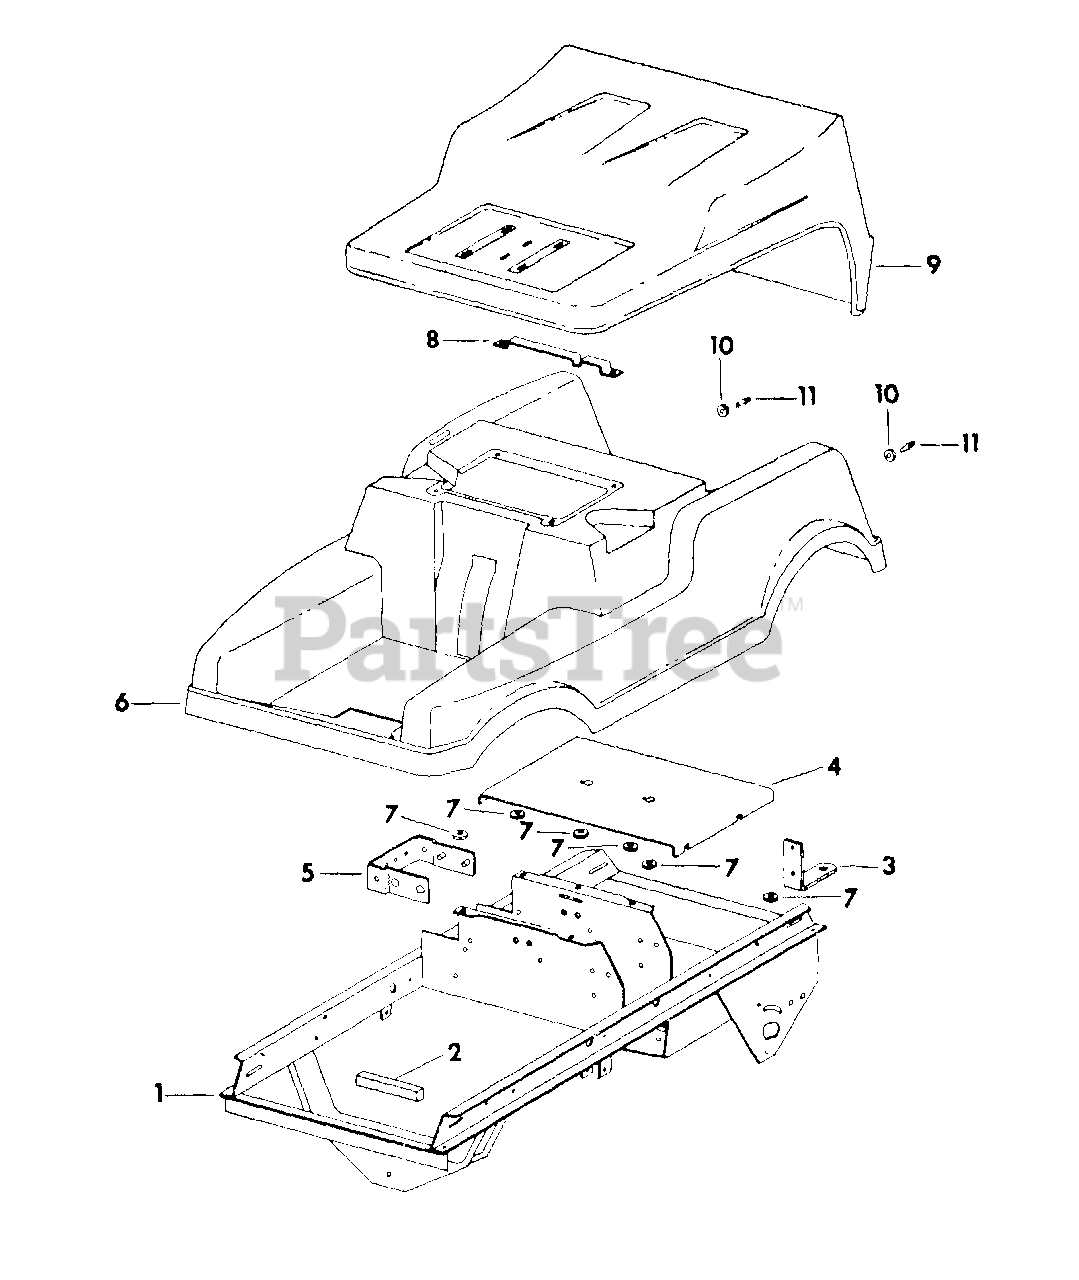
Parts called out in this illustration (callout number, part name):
1	FRAME ASSY, MAIN
2	SEAL, PRESS FRT REST
3	ANGLE DRAWBAR
4	PLATE BATTERY
5	BRACKET ASSY, SWITCH MOUNTING
6	BODY, MOWER
7	SPACER, BODY MTG.
8	SUPPORT SEAT
10	BUMPER, REAR COVER
